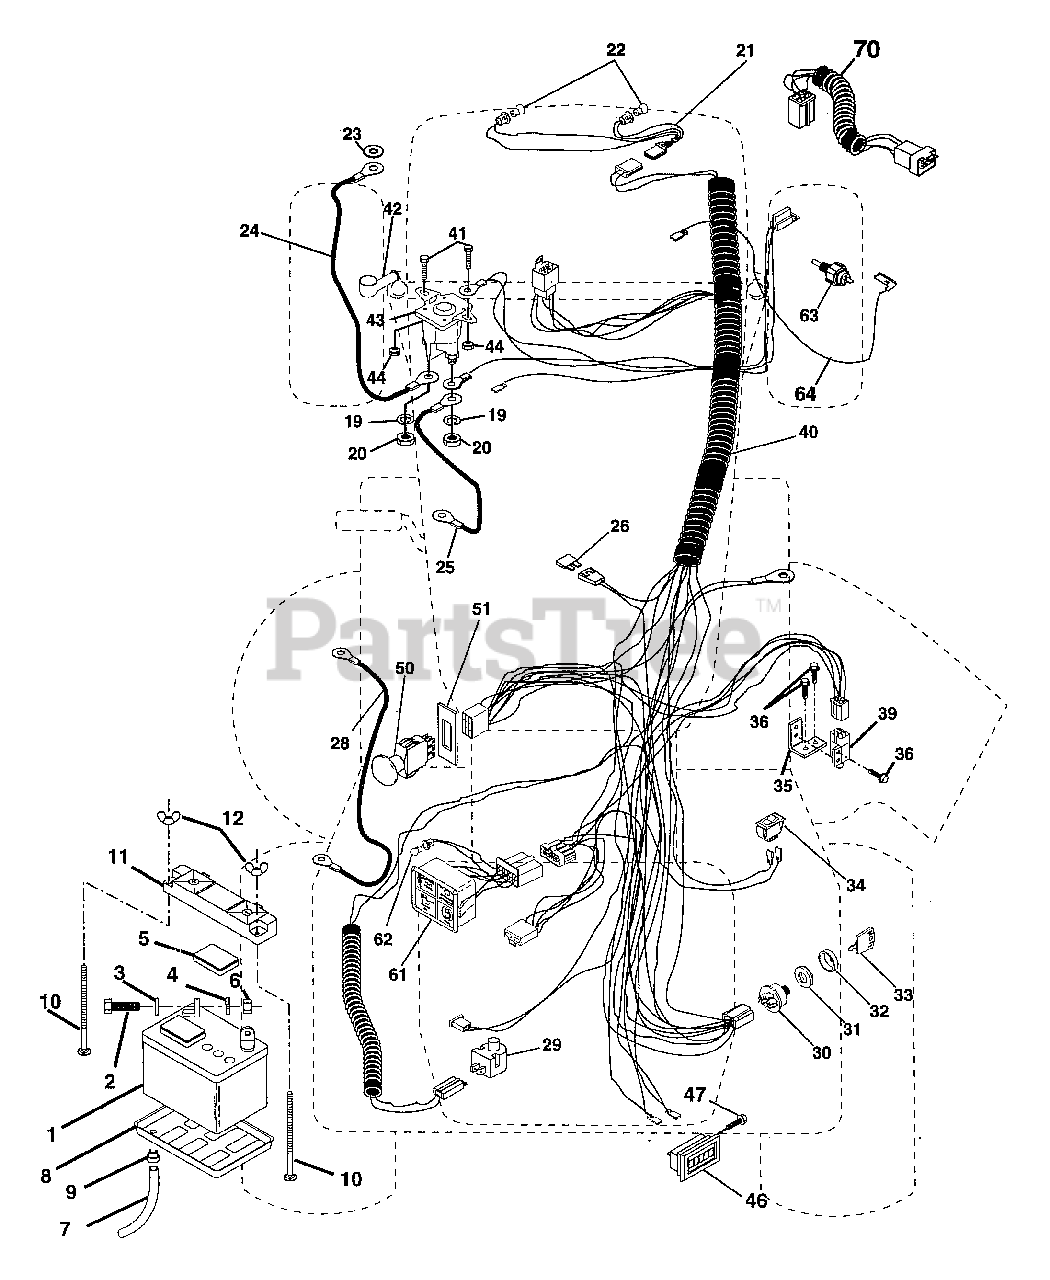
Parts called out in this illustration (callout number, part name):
1	Battery
2	Bolt, Hex Head 1/4-20 x 3/4
3	Washer 9/32 x 5/8 x 16 Gauge
4	Washer, Lock 1/4
5	Caps, Battery
6	Nut, Hex 1/4-20
7	Tube, Tray, Battery
8	Tray, Battery
9	Clamp, Hose
10	Bolt, Carriage 1/4-20 x 7-1/2
11	Guard, Terminal
12	Nut, Wing 1/4-20
19	Washer, Lock 1/4
20	Nut, Hex, Jam 1/4-20
21	Harness, Socket, Light
22	Bulb, Light
23	Washer, Lock, Internal Tooth 1/4
24	Cable, Starter, 6 Ga 11" Red
25	Cable, Battery
28	Cable, Battery
29	Switch, Plunger
30	Switch, Ignition
31	Nut, Ignition
32	Cover, Switch, Ignition
33	Key, Molded
34	Switch, Light
35	Bracket Switch Interlock
36	Screw, Hex Tap #10-24 UNC
39	Switch, Interlock (4 Terminal)
40	Harness, Ignition
41	Bolt, Hex 1/4-20 x 1/2 Grade 5
42	Cover, Terminal
43	Solenoid
44	Nut, Hex, Keps 1/4-20
46	Meter, Hour
47	Screw #10-24 x 1/2
50	Switch, P.T.O.
51	Ring, Retainer, Pto
58	Sensor, Low Voltage
61	Package, Light
62	Bulb, Light Package
63	Switch, Oil Sensor
64	Wire, Lead, Sentry, Kohler
70	Harness, Engine
